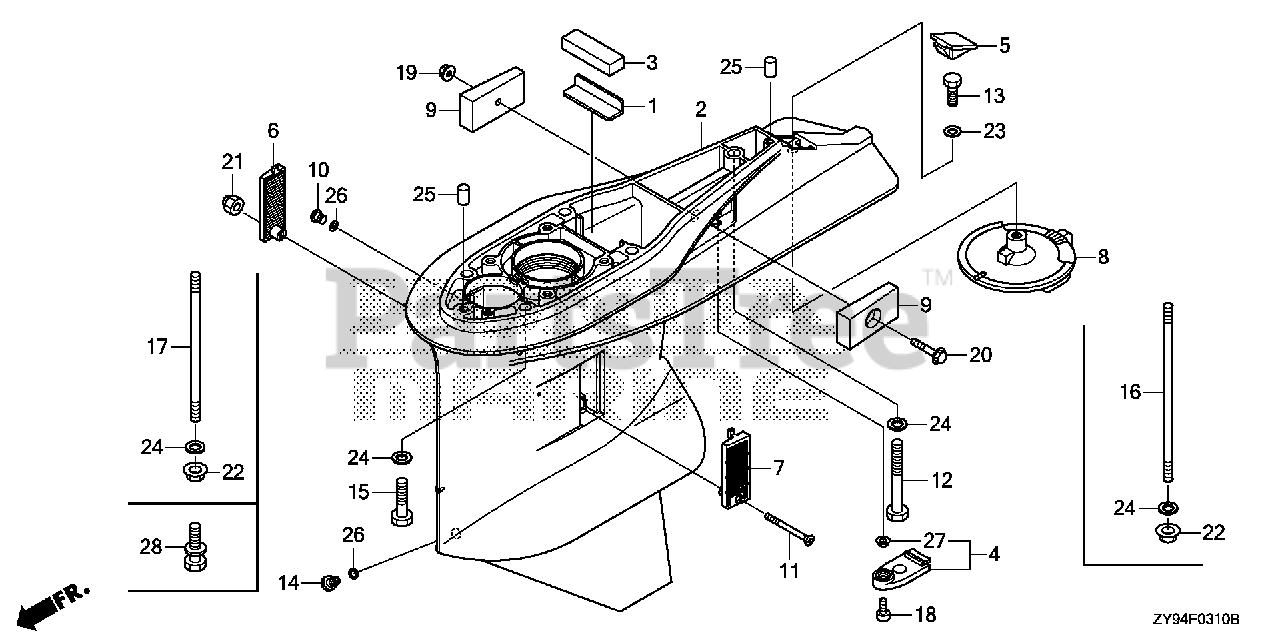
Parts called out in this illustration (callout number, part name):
1	PLATE, RUBBER SETTING
2	CASE, GEAR *NH282MU* (OYSTER SILVER METALLIC-U)
3	GROMMET, GEAR CASE
4	COVER B, GEAR CASE
5	GROMMET, GEAR CASE
6	SCREEN, R. WATER
7	SCREEN, L. WATER
8	TAB, TRIM *NH282MU* (OYSTER SILVER METALLIC-U)
9	METAL, ANODE
10	BOLT, OIL CHECK
11	SCREW, FLAT (5X55)
12	BOLT, HEX. (10X80)
13	BOLT, HEX. (8X25)
14	BOLT, DRAIN PLUG
15	BOLT, HEX. (10X40)
18	BOLT, SOCKET (6X16)
19	NUT, SELF-LOCK (6MM)
20	BOLT, FLANGE (6X35)
21	NUT, SELF-LOCK (5MM)
23	WASHER, PLAIN (8MM) Use up to Frame SN 4800712.
24	WASHER, PLAIN (10MM)
25	PIN, DOWEL (6X10)
26	O-RING (6.9X1.45)
27	COLLAR, DISTANCE (6.5X9X3)
